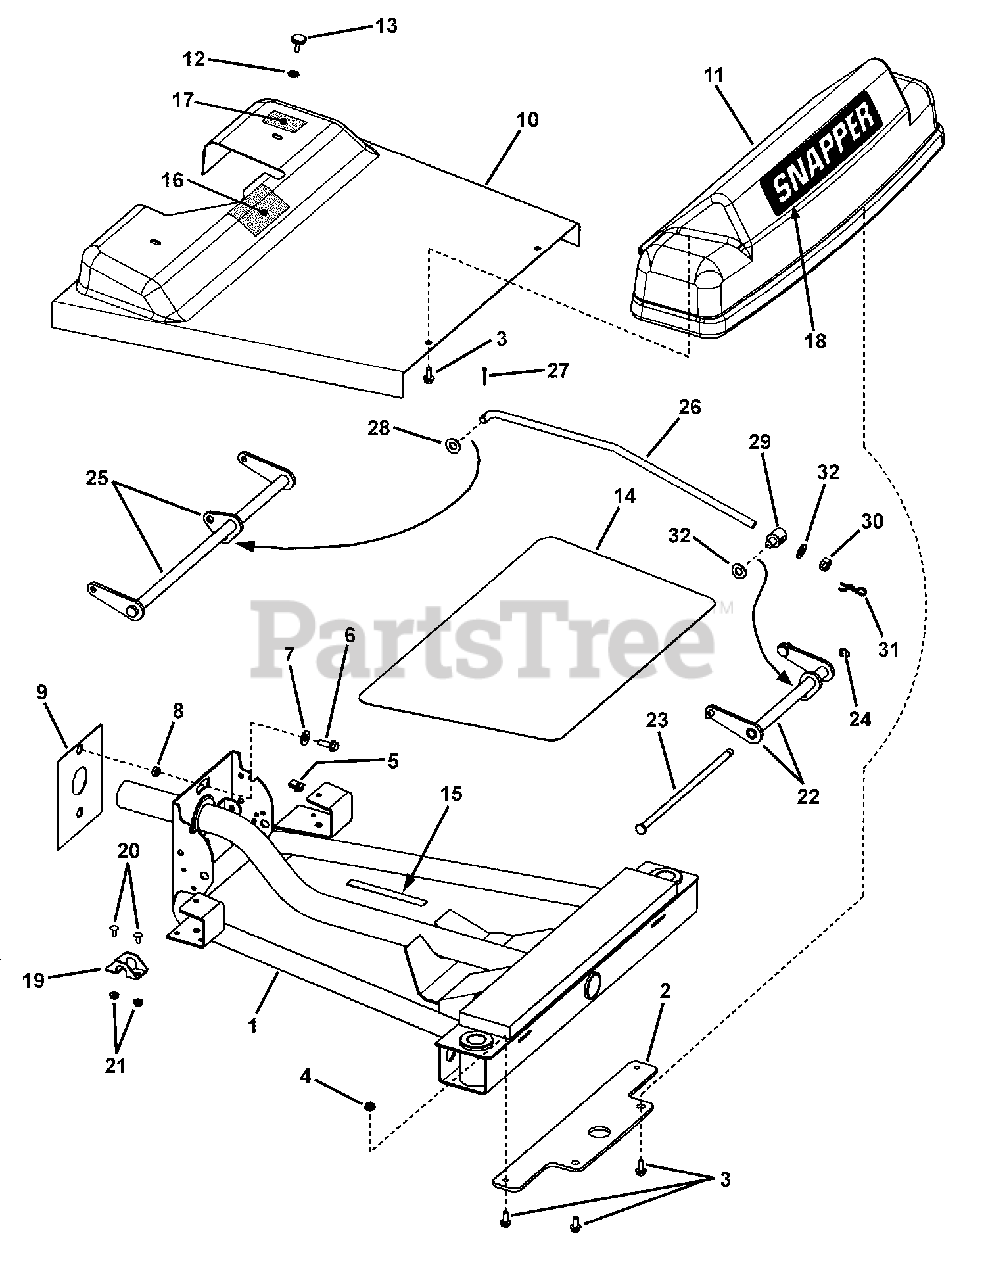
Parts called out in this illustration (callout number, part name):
1	WELDMENT, Front Frame Series 3
2	PLATE, Footrest Support
3	BOLT, 5/16-18 x 3/4" Hex Flange Lock
4	NUT, 5/16-18 Hex Flange Lock, GR5
5	FASTENER, "U" Type
6	SCREW, 3/8-16 x 1" Hex Washer Self-tap
7	WASHER, 3/8" FLAT (wide)
8	SPACER, Front Frame Pivot
9	PLATE, Front Frame Slip
10	FLOOR PAN, HOZ
11	FOOTREST, HOZ
12	WASHER, 1/4" Internal/External Lock
13	KNOB (1/4-20 thread)
14	MAT, Floor
15	PAD, Floor Board Support
16	DECAL, Warning, Read Manuals & Instructions
17	DECAL, Deck Height
18	DECAL, SNAPPER (14.56" long)
19	BRACKET, Saddle
20	BOLT, 1/4-20 x 5/8" Short Square Neck Carriage
21	NUT, 1/4-20 Hex Flange Lock
22	WELDMENT, Front Lift, 48
23	ROD, Deck Support
24	RING, .438 External Retaining
25	WELDMENT, Rear Lift
26	TIMING ROD, 48 (1/2-13 thread)
27	PIN, 1/8 x 1" Cotter
28	WASHER, 1/2 SAE Flat
29	SWIVEL, .50 Thru Hole
30	NUT, 1/2-13 Hex Center Lock, GR5 or B
31	HAIR PIN, 1/8 x 1/2"
32	WASHER, 1/2" SAE Flat
